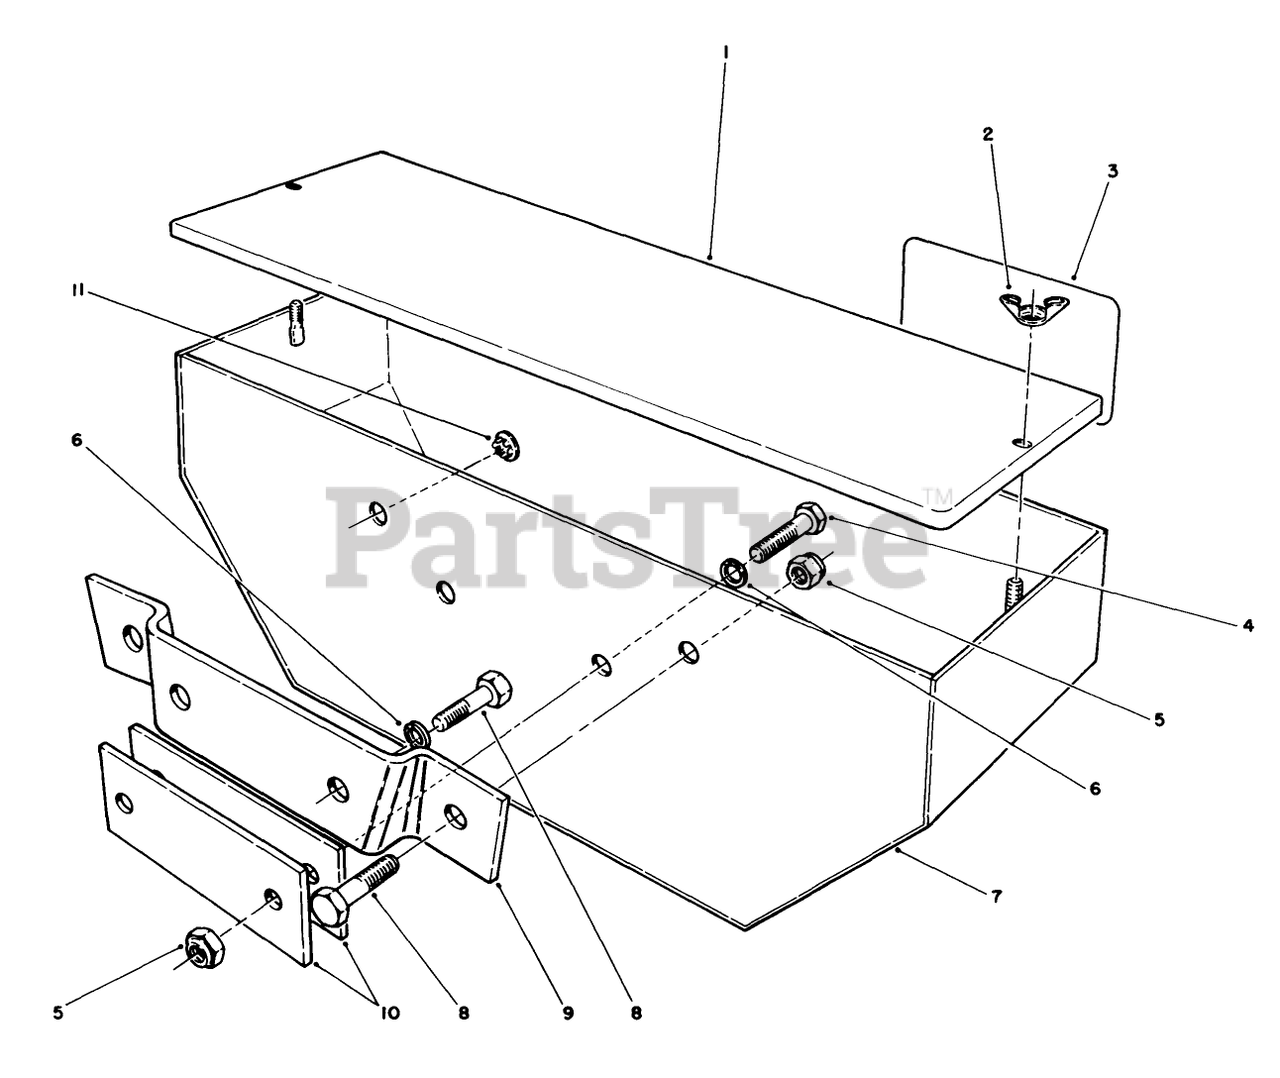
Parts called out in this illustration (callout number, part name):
1	WT BOX COVER R
2	NUT-WING
3	Decal
4	SCREW-HH
5	NUT-LOCK, NI
6	WASHER-LOCK
7	WEIGHT BOX WA
8	SCREW-HH
9	MOUNT BRKT R
10	SPACER PLATE
